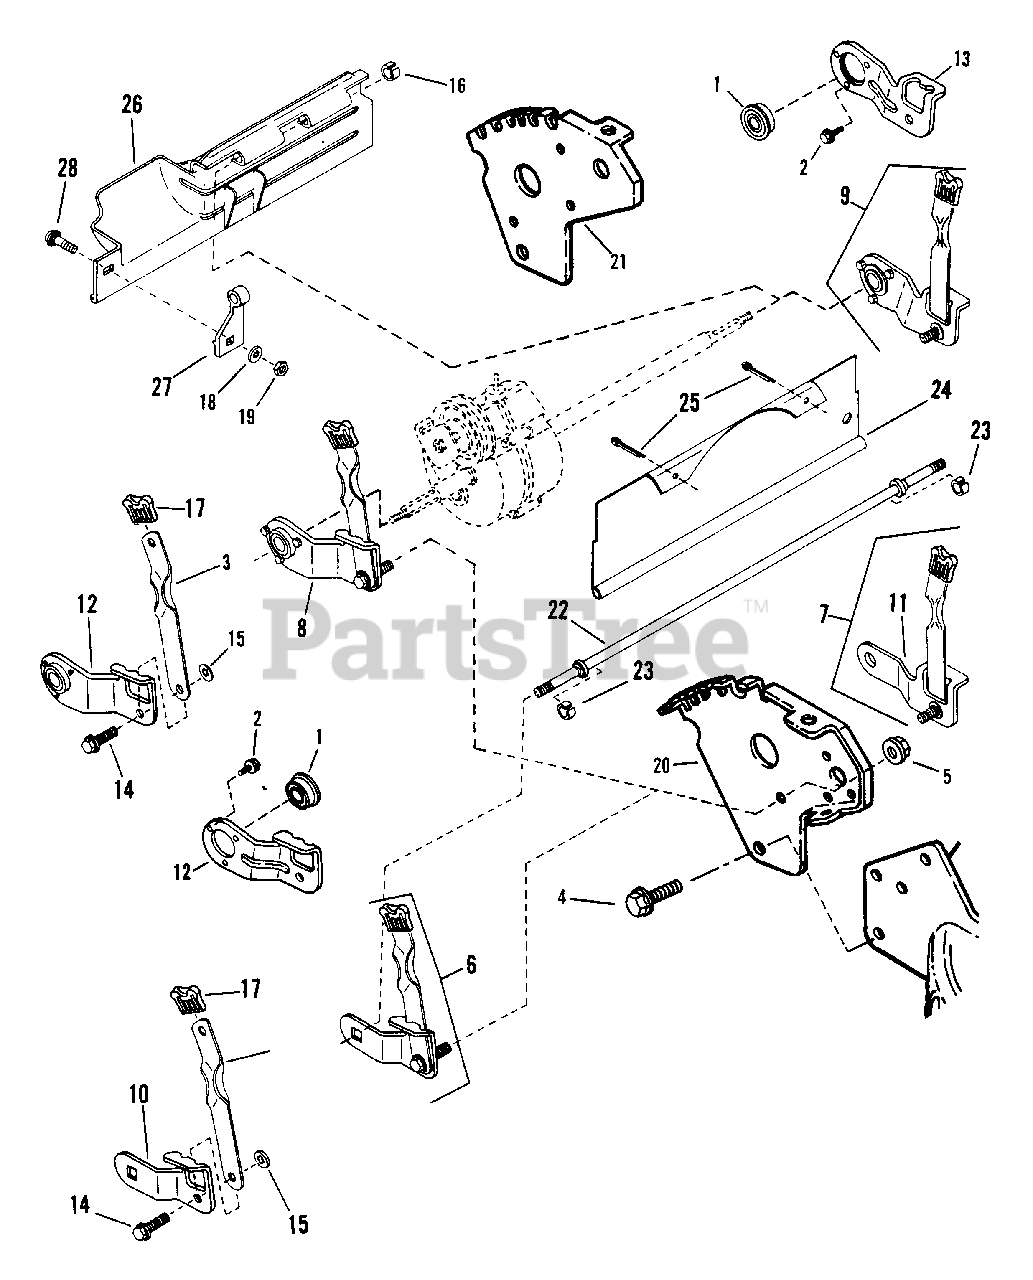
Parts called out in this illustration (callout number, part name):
1	BEARING
2	SCREW, #10-32 x 3/8" Self-Tapping
3	LATCH, Height Adjusting
4	SCREW, 5/16-18 x 5/8" Self-Tapping
5	NUT, 5/16-18 Hex Flange Lock
6	ASSEMBLY, Wheel Arm (Front Left & Rear Right)
7	ASSEMBLY, Wheel Arm (Front Right & Rear Left)
8	ASSEMBLY, Wheel Arm (Rear Right "P" Models)
9	ASSEMBLY, Wheel Arm (Rear Left "P" Models)
10	ARM, (Square Axle End)
11	ARM, (Round Axle End)
12	ARM, Wheel Rear Right "P" Models
13	ARM, Wheel Rear Left "P" Models
14	BOLT, 5/16-18 x 1" Shoulder
15	RETAINER, 5/16 Bolt
16	RING
17	GRIP, Latch
18	WASHER, 1/4 Internal Tooth Lock
19	NUT, 1/4-20 Hex
20	BRACKET, Right Rear Wheel
21	BRACKET, Left Rear Wheel
22	AXLE
23	RING
24	GUARD, Rear Foot
25	PIN, 1/8 x 1-1/2" Cotter
26	GUARD, Rear Foot
27	SUPPORT, Foot Guard
28	BOLT, 1/4-20 x 1/2" Short Neck Carriage (Gr.5)
